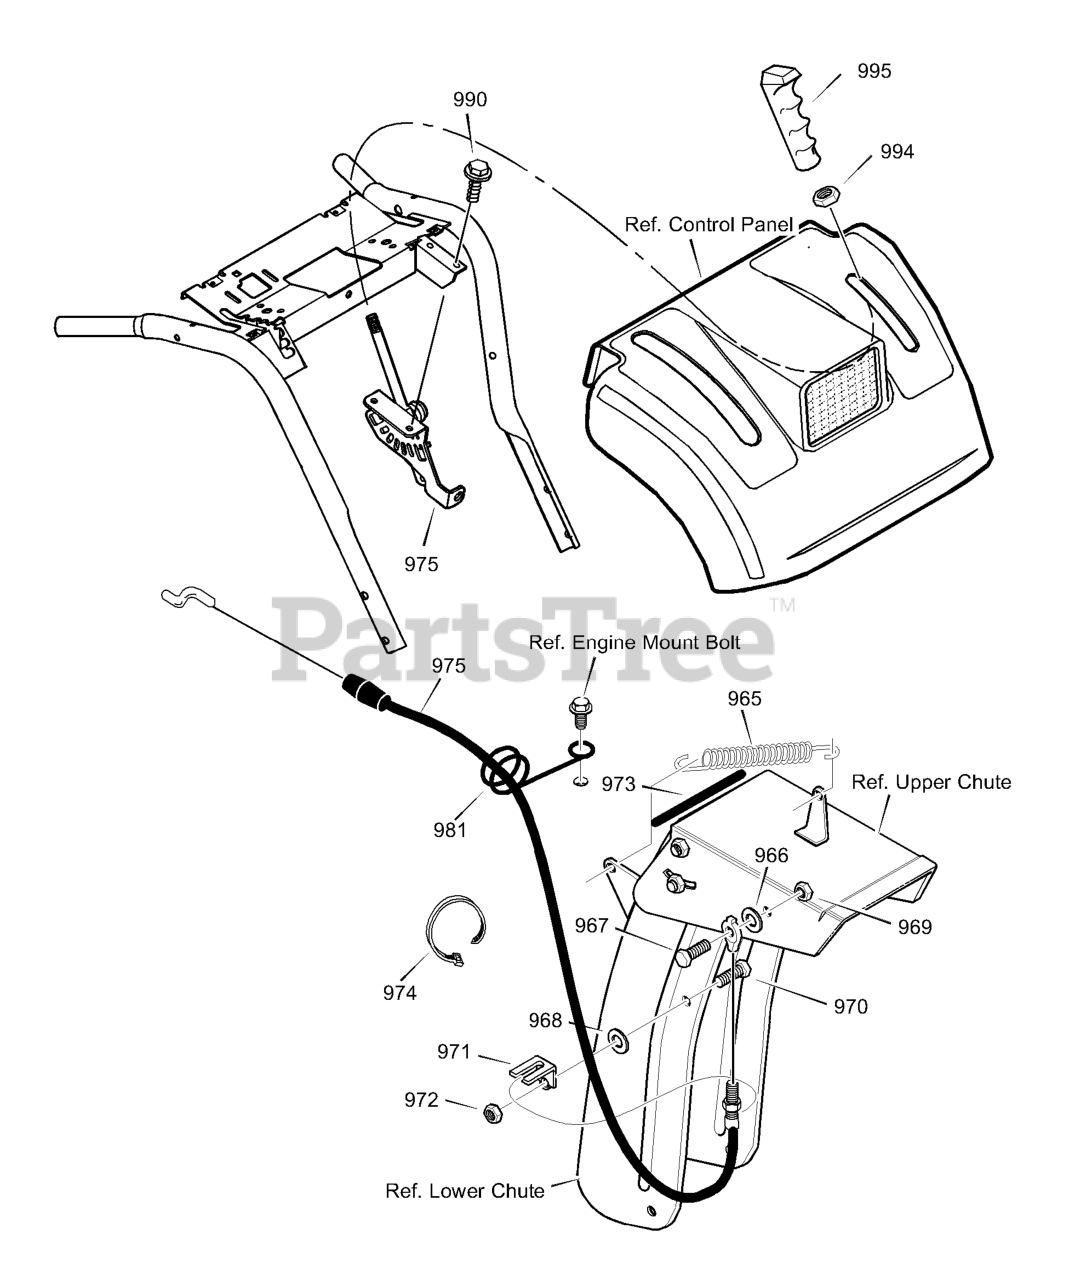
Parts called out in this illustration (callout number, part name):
965	SPRING, TENSION RETURN
966	WASHER, FLAT
967	BOLT, 5/16-18
968	WASHER, FLAT
969	NUT, 1/4-20
970	SCREW, 5/16-18 x 0.75
971	BRACKET, CABLE CHUTE
972	NUT, 5/16-18
974	TIE, CABLE
975	CABLE, CHUTE CONTROL
981	WIRE FORM
990	SCREW, 3/8-16 x 1.75
994	NUT, 3/8-16 HEX JAM
995	HANDLE, 3/8-16 MOLDED
